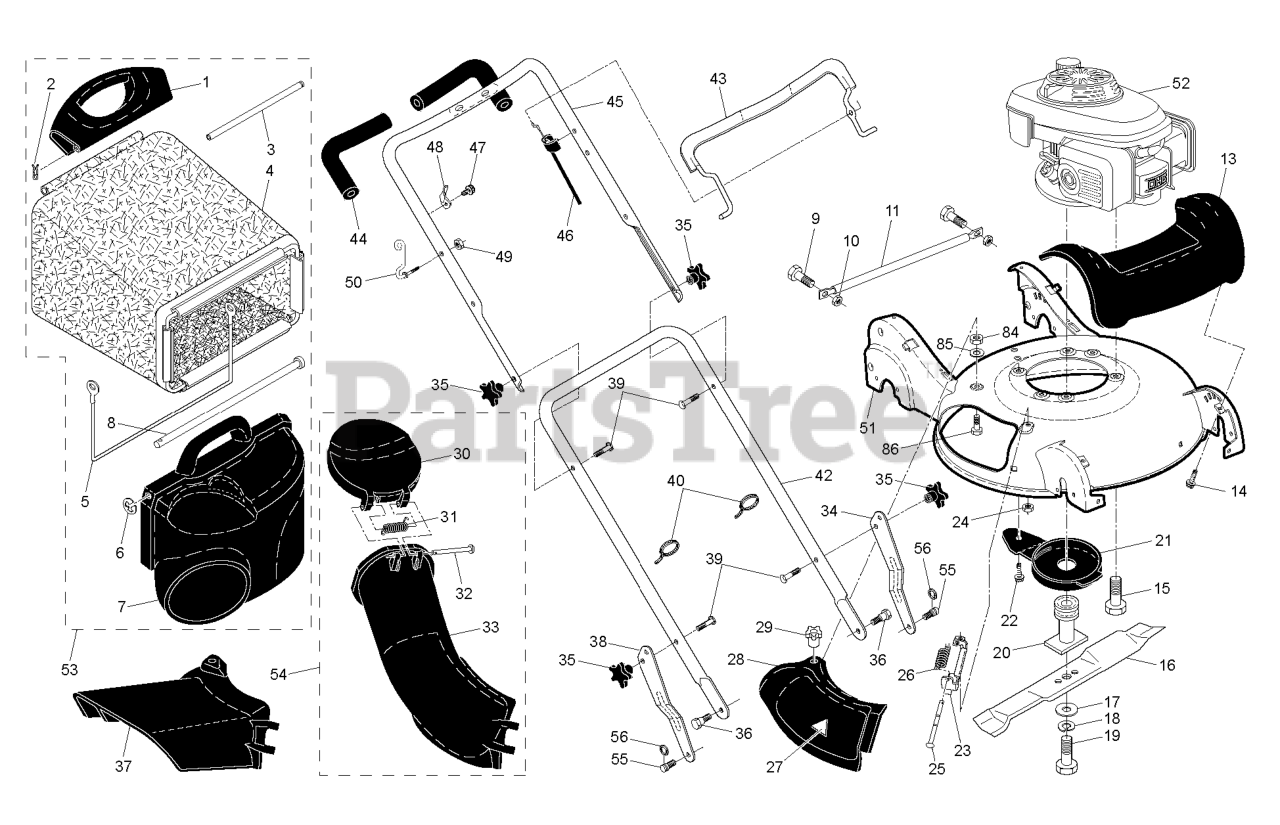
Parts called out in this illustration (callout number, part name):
1	HANDLE.GRASSBAG.REAR.H-GRAY
2	COTTER PIN (3 2)(2 2MC)
3	ROD.REAR.HANDLE.YELLOW
5	FRAME, GRASSBAG
7	DOOR, GRASSBAG
8	ROD, PIVOT
10	LOCKNUT.NYLOC.1/4-20
11	TUBE, REAR SKIRT
13	COVER.FRONT.21.HV.H-GRAY
14	SCREW, HEX WASHER HEAD
15	BOLT 3/8-16X1-1/8
16	Blade, 21"
17	WASHER,HARDEN
18	LOCKWASHER
19	BOLT.HD.HEAD.3/8-24X2.50 (2 2)
20	ADAPTER.BLADE
21	DEBRIS SHEILD
22	SCREW 1/4X20
24	NUT.HEX.FLANGE.1/4
25	ROD.HINGE.1/4"3.82"
26	SPRING.MULCH.DOOR
27	DECAL.INTERNATIONL.CUTFINGER
28	MULCHER DOOR
29	KNOB.MULCH.DOOR
30	CHUTE.DOOR.21.HV.H-GRAY
32	ROD.HINGE.1/4"3.82"
33	DISCHARGE CHUTE PLASTIC
34	ADJUSTMENT BRACKET, LOWER LH
35	KNOB.HANDLE.PLASTIC.STAR.BLACK
36	SCREW.5/16X.680.TRIM.H
37	GUARD.CLIP.ON.21.HV.GRAY
38	BRACKET.ADJ.LOWER.HDL.RT.GREY
39	BOLT, HANDLE 5/16-18X1.75
40	TIE GUIDE
42	HANDLE.LOWER.GREY
43	BAIL CONTROL
44	GRIP.HANDLE.FOAM.WIDE.(1 SIDE)
45	HANDLE.ASM.UPPER.W/GRIP
46	CABLE.MZR.50.SNAP-IN
48	BRACKET
49	NUT
50	GUIDE.ROPE.WALK.MOWER
53	Grassbag Assembly, Complete
54	CHUTE.LOWER.ASM.WALK.MOWER
55	STUD.SHOULDER.T45.BZP
56	E-RING 7/16 RE
84	NUT, HEX
85	LOCKWASHER
86	BOLT.CARRIAGE.1/4-20 X 7/8
